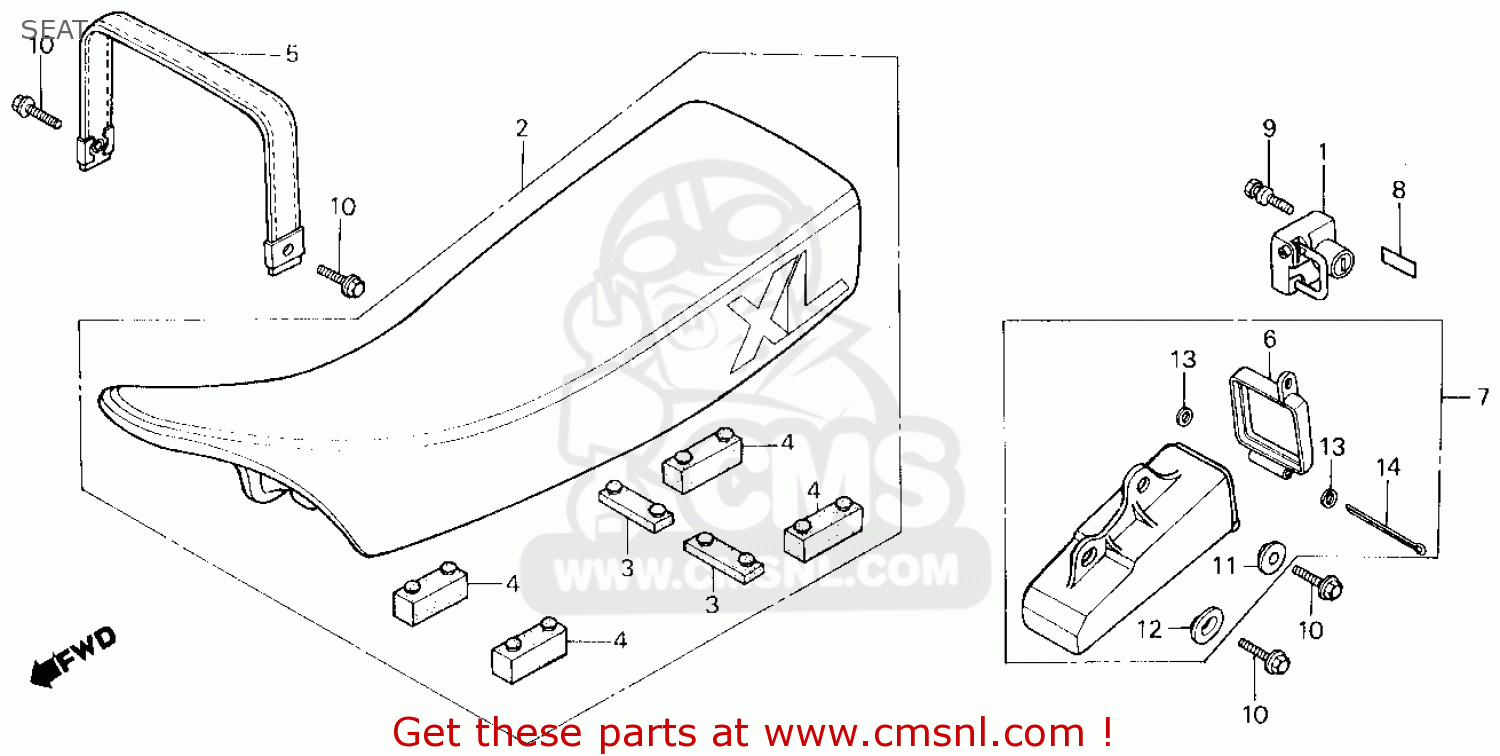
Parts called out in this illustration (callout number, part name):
1	HOLDER,HELMET
2	SEAT ASSY,DOUBLE
3	RUBBER,SEAT SET
4	RUBB,A.SEAT SETTI
5	BELT COMP.,SEAT
6	CAP,TOOL BOX
7	BOX ASSY.,TOOL
8	LABEL,HELMET HOLD
9	BOLT,B,SPECIAL
10	BOLT,FLANGE,6X16
11	WASHER,6X20
12	WASHER,6X9
13	WASHER 3MM
14	PIN COTTER 3.0MM
